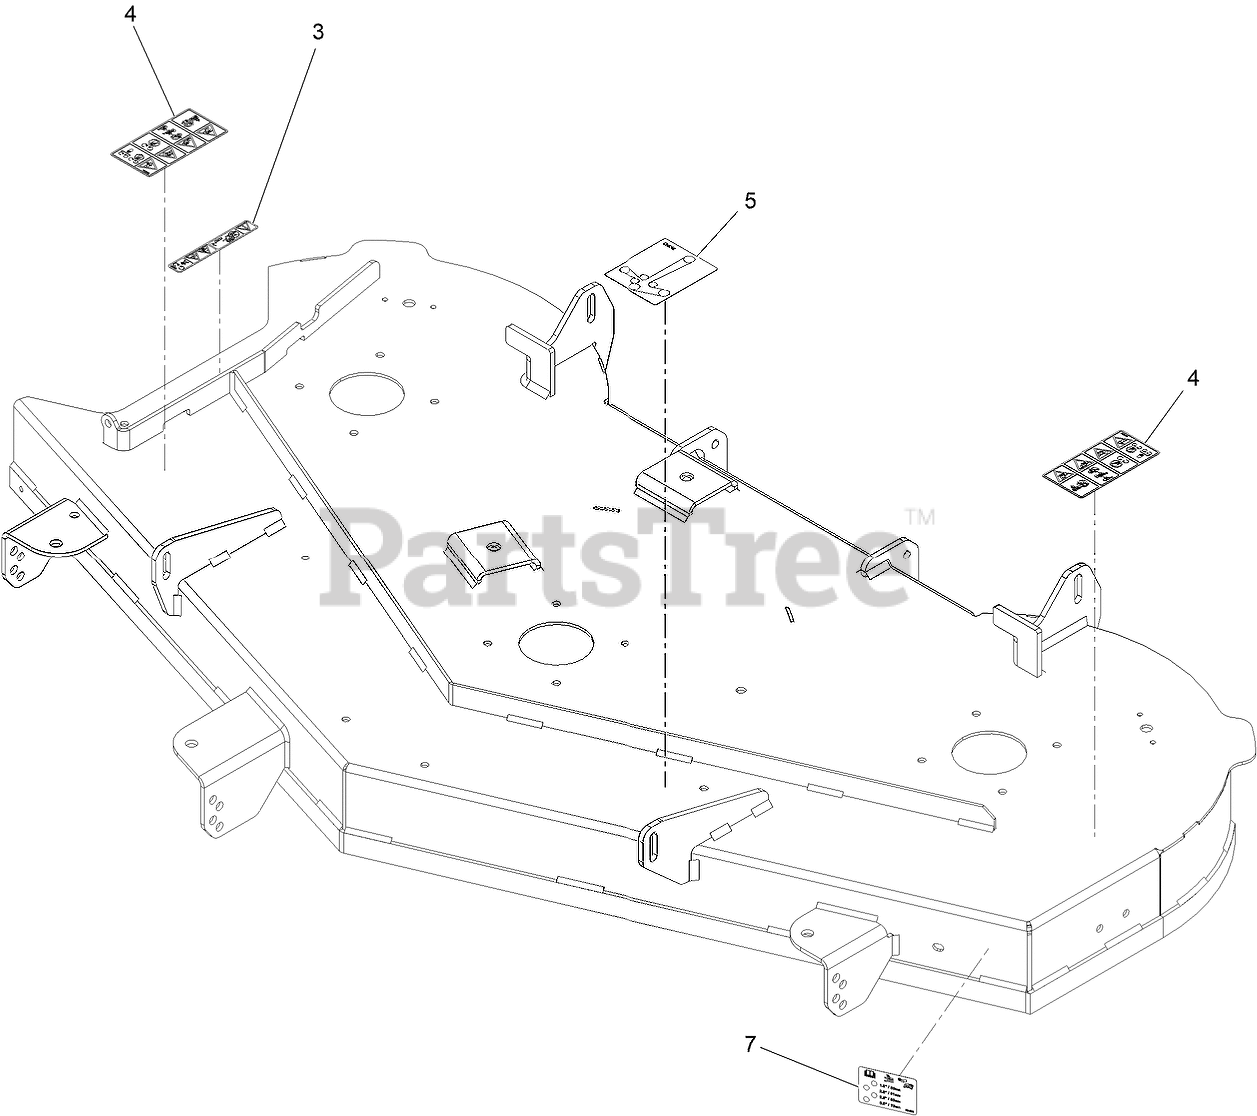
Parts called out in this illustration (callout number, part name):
3	DECAL-DANGER
4	DECAL-DANGER, DECK
5	DECAL-ROUTING, BELT
7	DECAL-SCALP, ANTI
